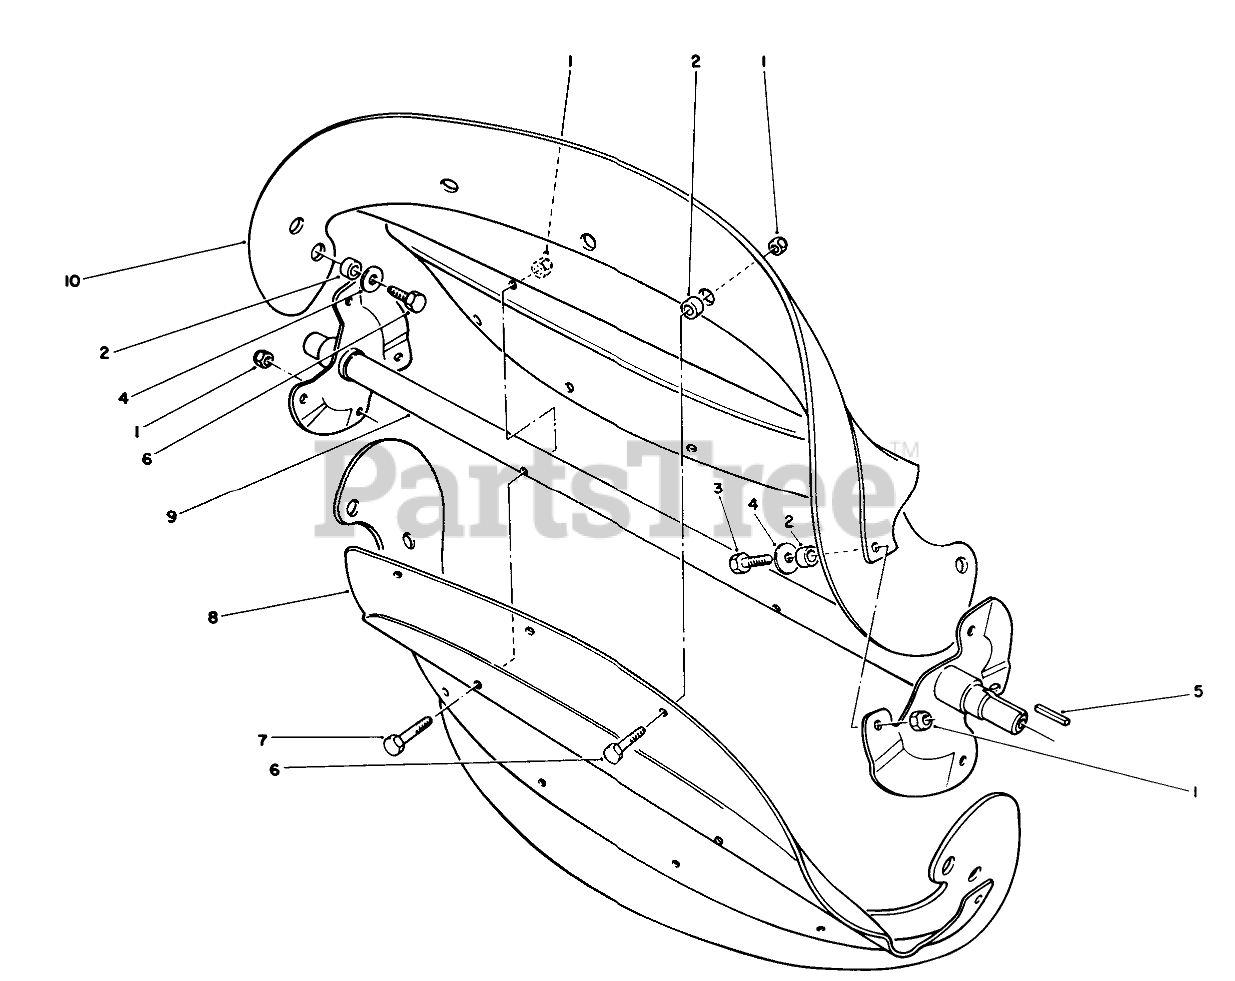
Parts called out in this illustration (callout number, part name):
1	NUT-LOCK, NI
2	SPACER-BLADE, ROTOR
3	SCREW-HH
4	WASHER-FLAT
5	KEY-SQUARE
6	SCREW-HH
7	SCREW-HH
8	ROTOR
9	Rotor Shaft Assembly
10	Blade-Rotor
